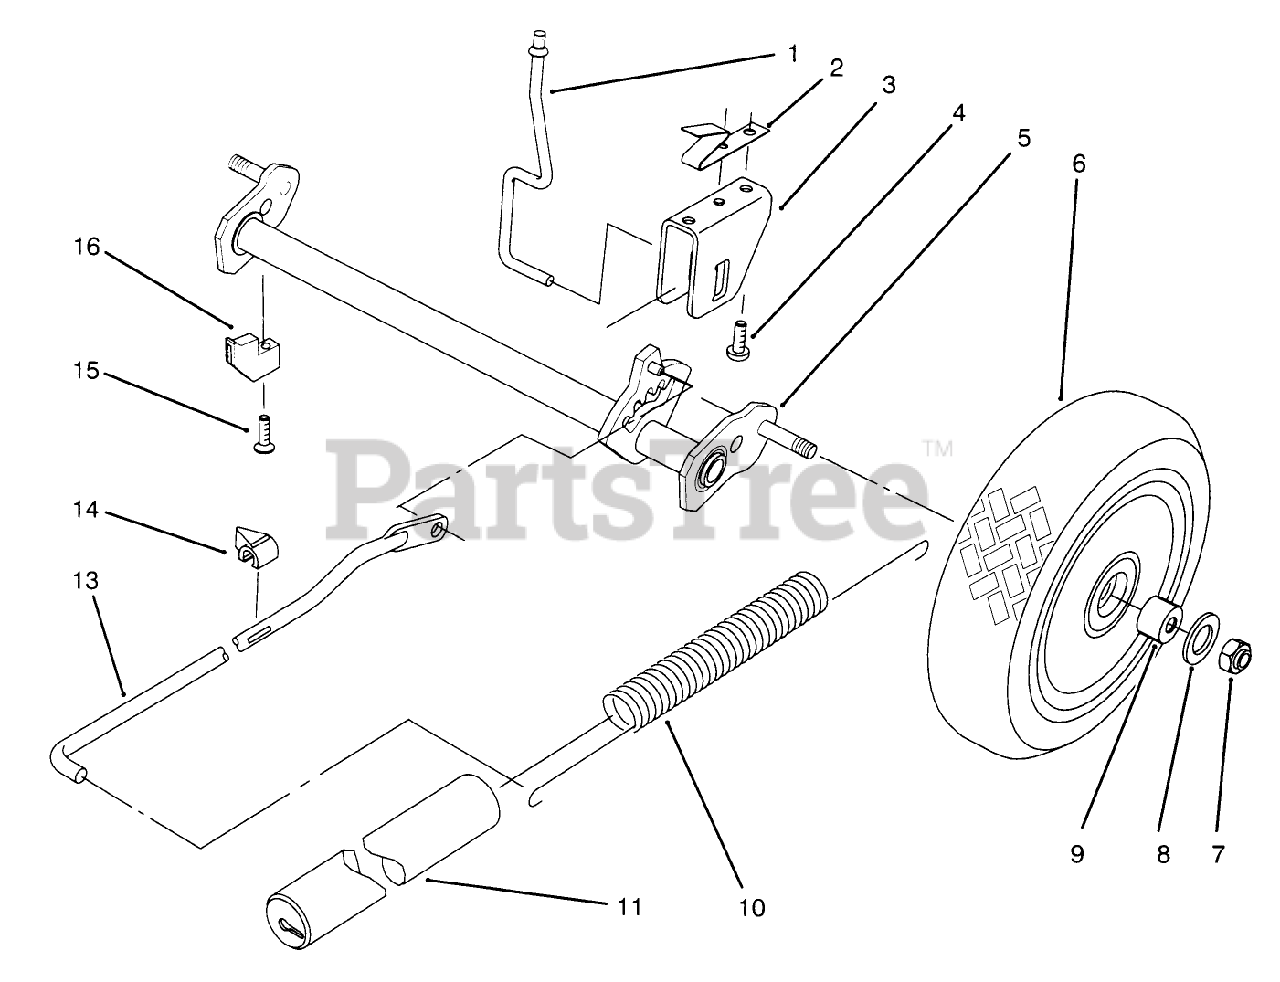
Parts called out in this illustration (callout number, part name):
1	Rod-Trigger
2	SPRING-RETURN, TRIGGER
4	SCREW-RH
5	AXLE-REAR
6	WHEEL-REAR
7	NUT-HH
8	WASHER-WHEEL
9	BUSHING
10	SPRING-COUNTERBALANCE
11	COVER-SPRING
14	INDICATOR-HEIGHT OF CUT
